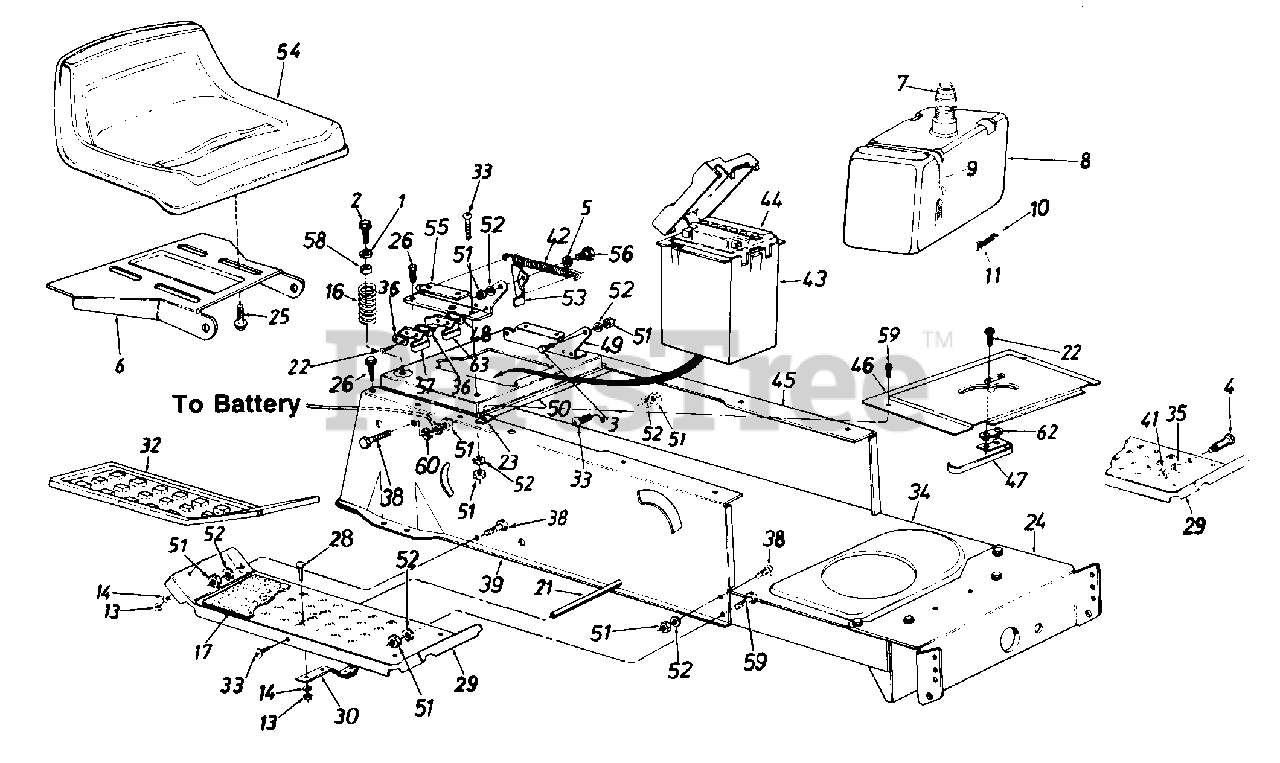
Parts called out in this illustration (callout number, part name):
1	Fl-Wash. .344" I.D. x .875"
2	Hex Wash. Hd. Tap Scr. 5/16-18 x 1.25" Lg.
3	Shld. Bolt .437" Dia. x .162"
4	Shld. Bolt .50" Dia. x .84"
5	Spr-Wash. .445" I.D. x .75
6	Seat Pivot Bracket
7	Fuel Cap w/o Gasket
8	Fuel Tank
9	Tie Strap
10	Fuel Line
11	Hose Clamp
13	Hex Nut 1/4-20 Thd.
14	L-Wash. 1/4" I.D.
16	Compression Spring
17	Foot Pad
21	Running Board Rod
22	Hex Wash. Hd. AB-Tap Scr. #8 x .50" Lg.
23	Speed Nut #10Z
24	Front Pivot Brkt.
25	Hex Tap Scr. 3/8-16 x .75"
26	Hex Wash. Hd. AB-Tap Scr. 5/16 x .75" Lg.
28	Carriage Bolt 1/4-20 x .62"
29	Running Board
30	Blade Brake Ass'y.
32	Rubber Foot Pad-L.H.
33	Truss Mach. Scr. 5/16-18 x .75" Lg.
34	Lower Frame
35	L-Wash. 3/8" I.D.
36	Insulator Plate
38	Hex Bolt 5/16-18 x .75" Lg.
39	Upper Frame-R.H.
41	Hex Nut 3/8-16 Thd.
42	Extension Spring 5.31" Lg.
43	Battery Box w/Cover
44	12-V Battery
45	Upper Frame-L.H.
46	Shift Cover
47	Reverse Safety Switch
48	Insulator Boss Plate
51	Hex Nut 5/16-18 Thd.
52	L-Wash. 5/16" I.D.
53	Seat Lift Brkt.
54	Seat 8-718" High
57	Spring Switch
58	Bushing
59	Truss Hd. Scr. 5/16-18 x 1.0" Lg.
60	External L-Wash. 5116" I.D.
62	Insulator Nut Plate
63	Safety Switch
